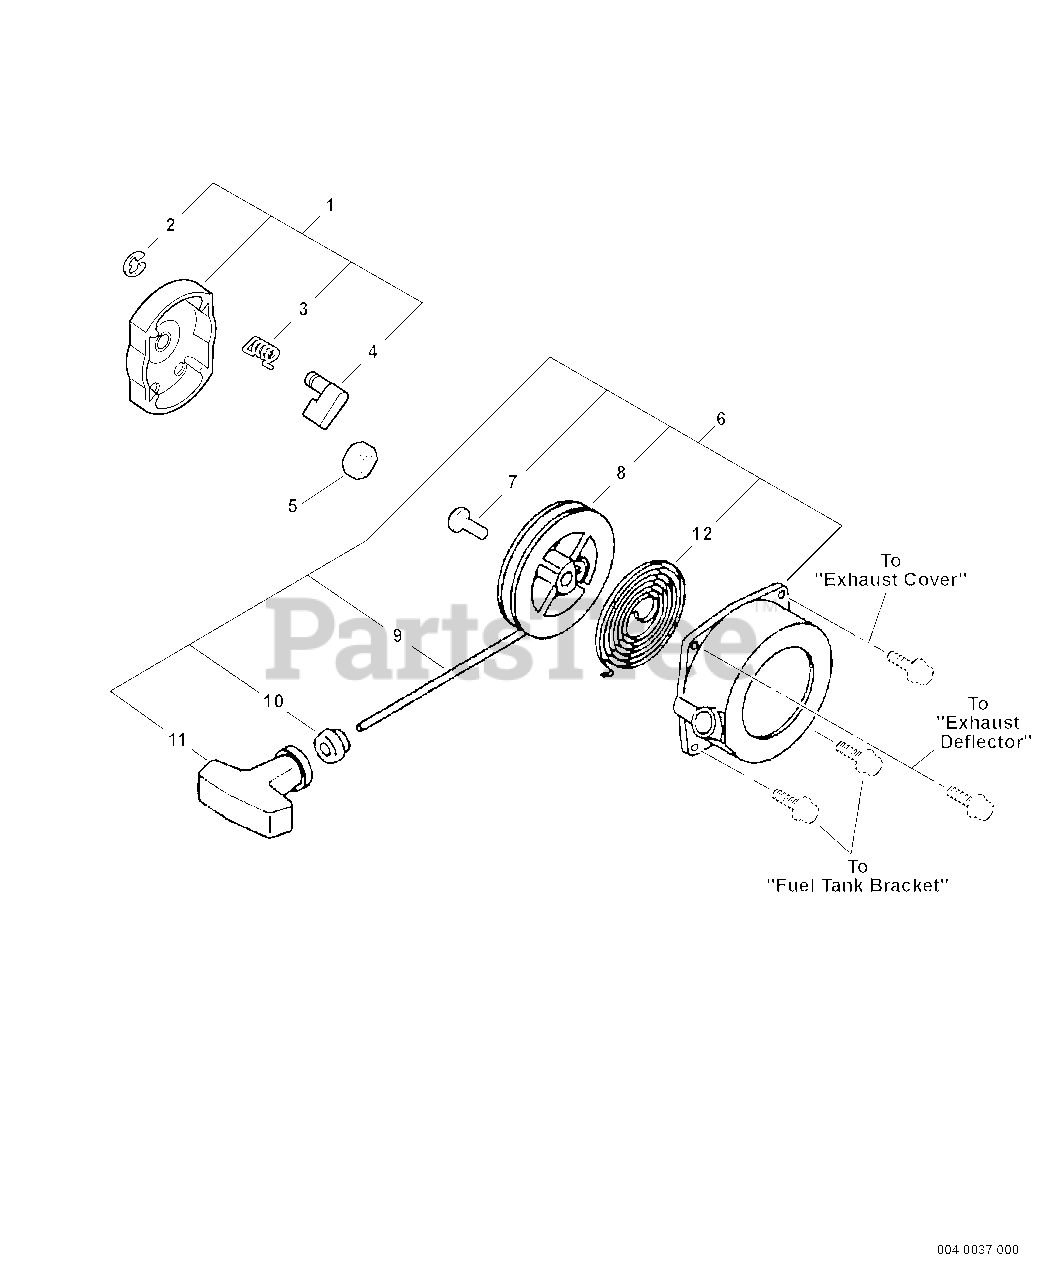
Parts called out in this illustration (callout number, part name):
1	STARTER PAWL ASSY
2	RING, RETAINING - 4
3	SPRING, RETURN
4	PAWL, STARTER
6	STARTER ASSY
8	REEL, ROPE
9	ROPE, STARTER - 3.5X1000
10	GUIDE, ROPE
11	GRIP, STARTER
12	SPRING, REWIND
